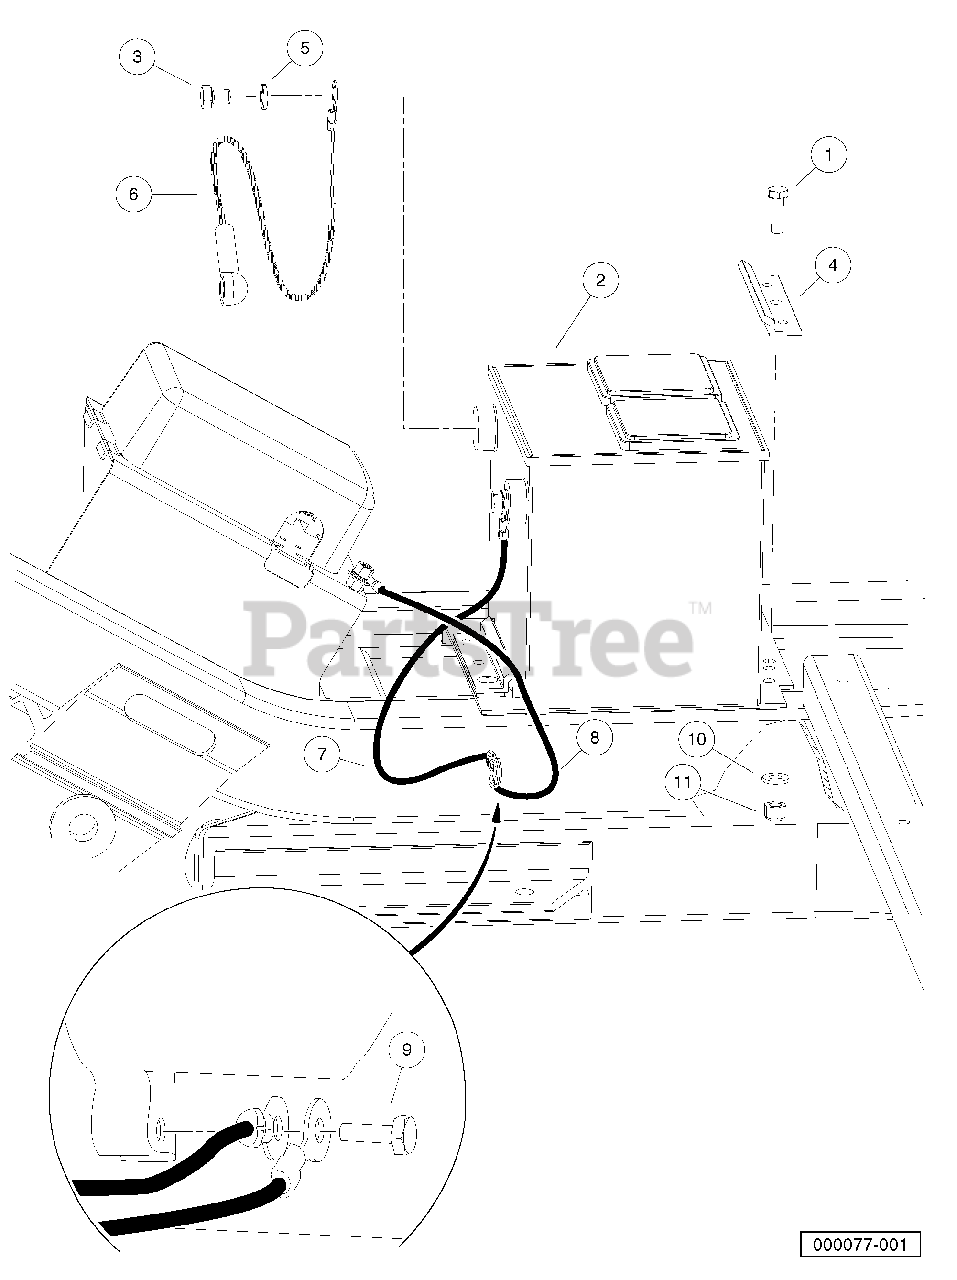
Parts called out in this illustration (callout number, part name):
1	Screw, 5/16-18 X 1.00 Hex Cap
2	Battery, 12-Volt
3	Screw, 3/8-16 X 0.50 Stainless Steel Hex-Head
4	Clamp, Battery
5	Lockwasher, 3/8 Stainless Stl
6	Asm, #6 Red Wire
7	Asm, #6 Blk Wire
8	Asm, #6 Blk Wire
9	Bolt, M6 X 1 X 16 Loctite
10	Washer, 5/16 Type A Flat
11	Locknut, 5/16-18 Nylon Insert
